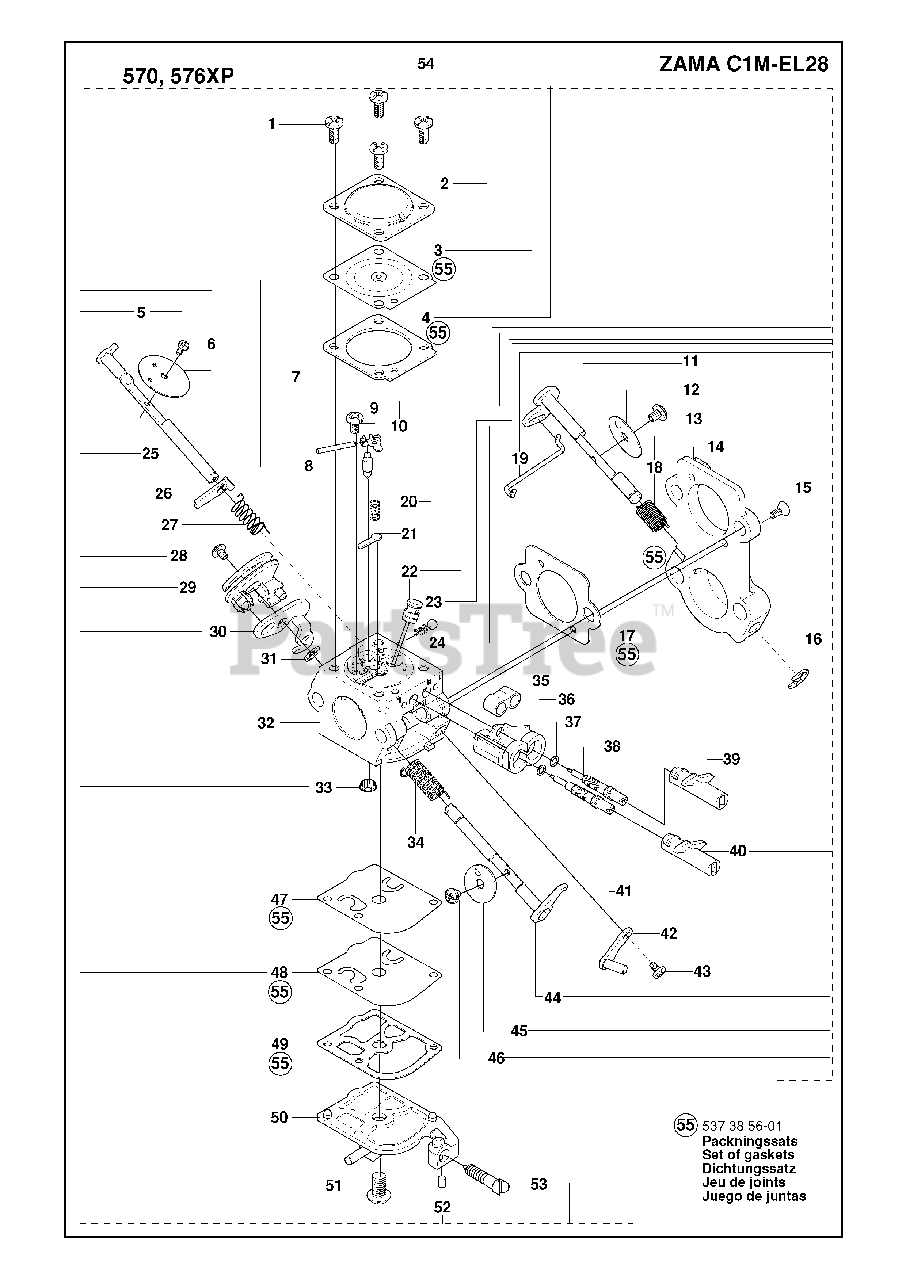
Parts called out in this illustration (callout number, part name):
6	CHOKE FLAP
7	PIN FULCRUM
8	INLET NEEDLE
12	THROTTLE FLAP
14	RP CARBURETOR
25	CHOKE SHAFT
32	RP CARBURETOR
38	NEEDLE HIGH SPEED
41	LOW SPEED NEEDLE
44	THROTTLE SHAFT
47	PUMP DIAPHRAGM
54	RP CARBURETOR
55	GASKET SET
